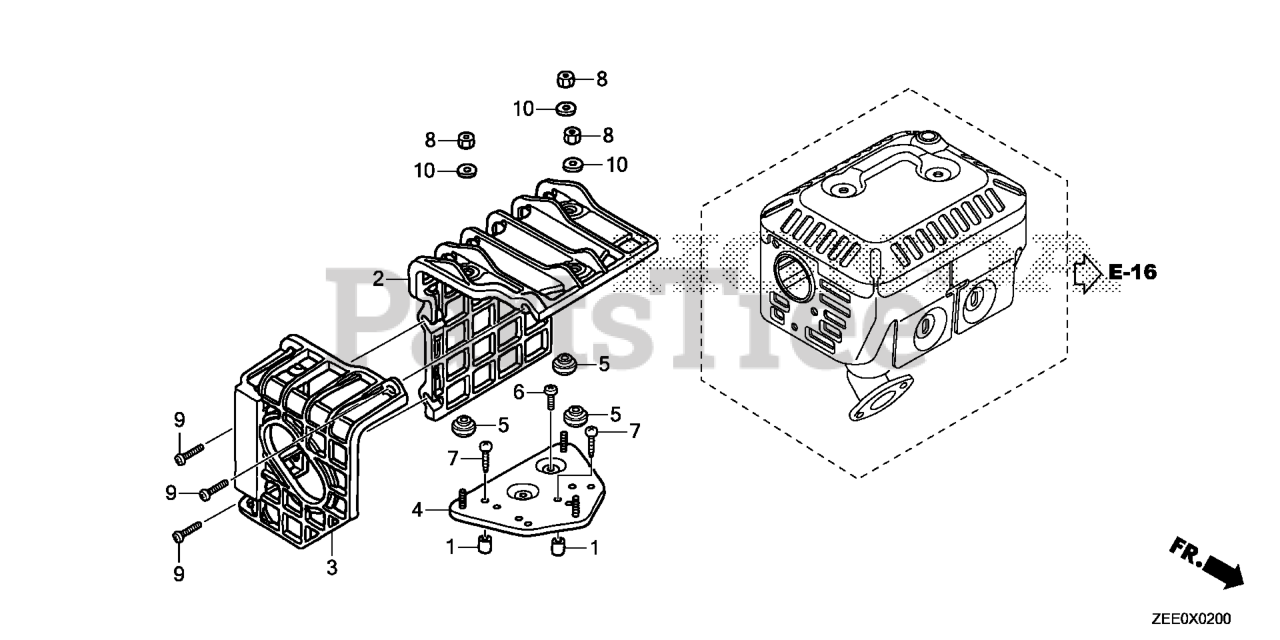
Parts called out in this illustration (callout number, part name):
1	COLLAR, AIR CLEANER HOUSING
2	COVER, MUFFLER
3	COVER, RR. MUFFLER
4	BASE, MUFFLER COVER
5	SPACER, MUFFLER COVER
6	SCREW, TAPPING (5X8)
7	SCREW, TAPPING (5X25)
8	NUT, HEX. (5MM)
9	SCREW-WASHER (6X20)
10	WASHER, PLAIN (5MM)
